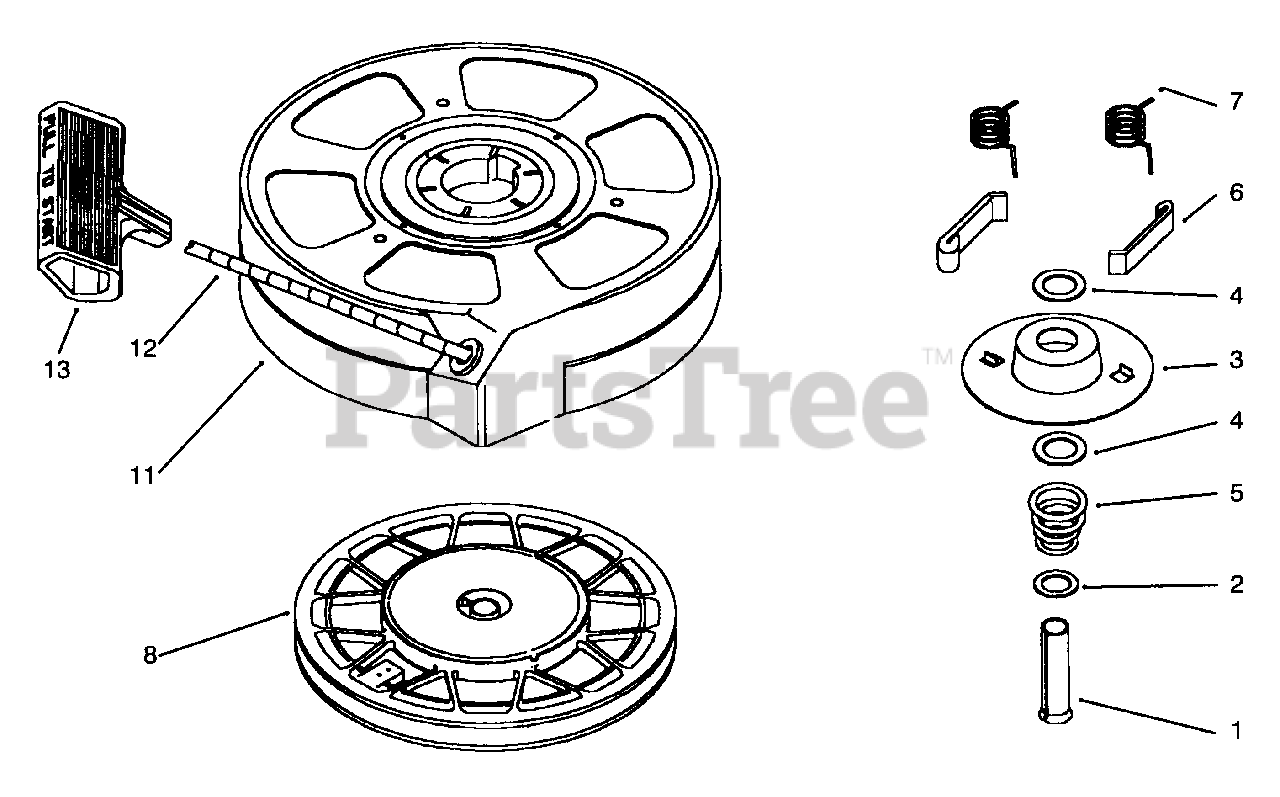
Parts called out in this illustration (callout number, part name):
1	Pin-Spring
3	Retainer
5	Spring-Brake
6	Dog-Starter
7	Spring-Dog
8	Pulley & Spring-Rewind
11	Housing Assemble-Starter
12	Rope-Starter
13	Handle Assembly
